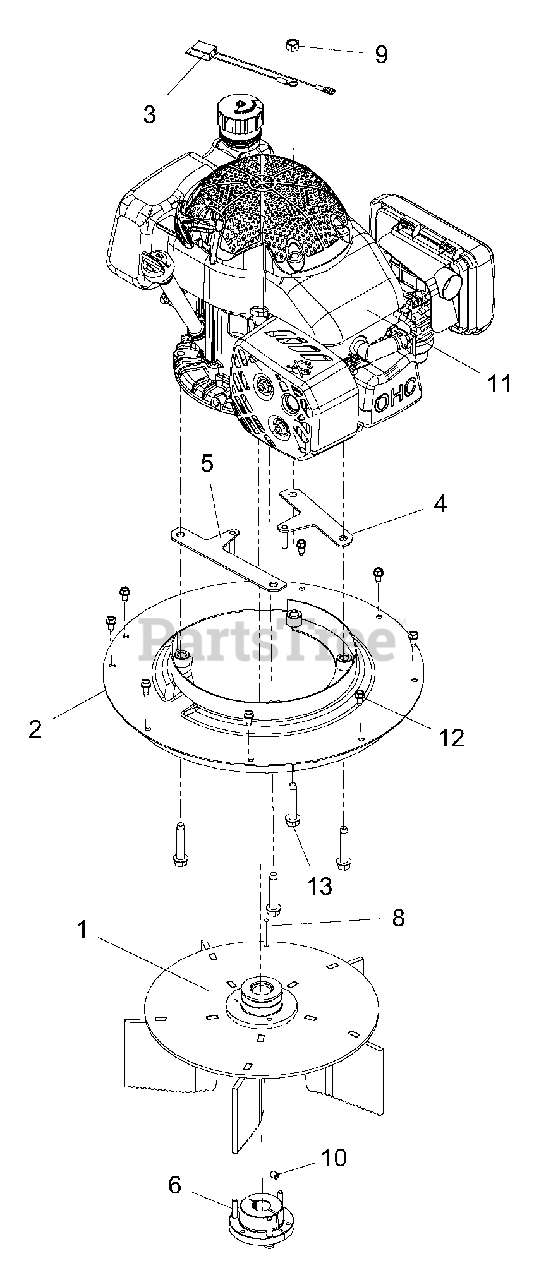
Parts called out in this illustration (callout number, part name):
1	WLDMT, IMPELLER - APV TAPER
2	WLDMT, ENGINE PLATE - RED
3	HARNESS, WIRE APV
4	WLDMT, BRKT - APV BELT FNGR S
5	WLDMT, BRKT - APV BELT FNGR R
6	BUSHING, TAPER - SPLIT 7/8" (SDS)
6	BLT-HEX .25-20 X 1.5 FTHD GR5 ZC
6	@WSHR-LK .25 X .062 REG YWZC
8	KEY-SQ .188 x .188 x 1.50 SAE 8630
9	NUT-LK-CTR .38-16 YWZC
10	SCR-SET, 31-18 x .38 SKHCUPDL REV
11	ENGINE, SUBARU - EA190 (CE)
12	SCR-TAP .25-20 x .50 HWH TR YWZ
13	SCR-TAP .38-16 x 2.00 HWH TR YZ
